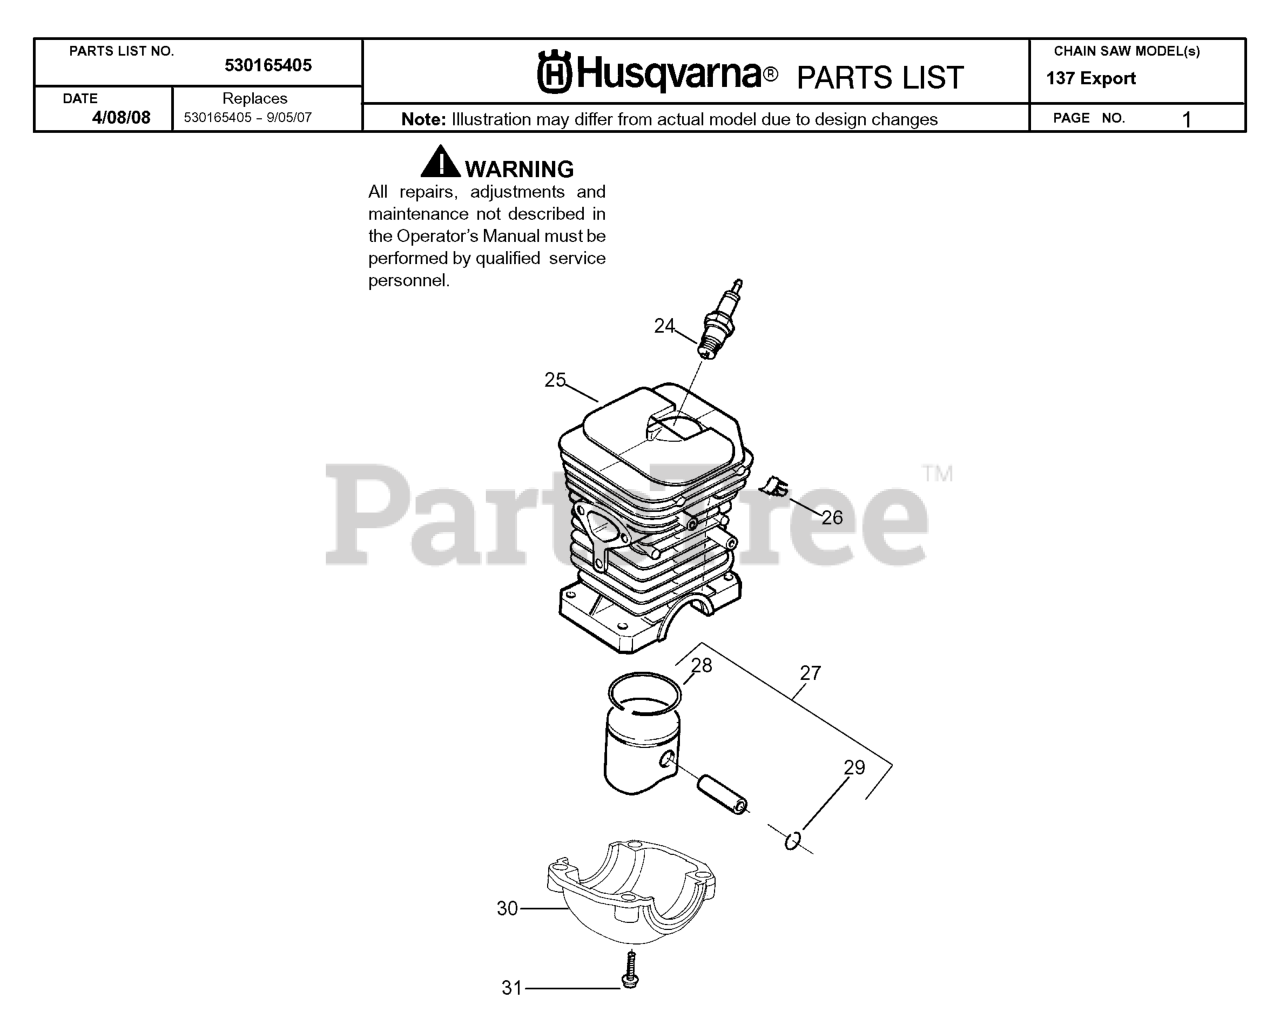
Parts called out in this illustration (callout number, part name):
24	Spark Plug (RCJ--7Y)
25	CYLINDER ASSY/136
26	CLIP - HIGH TENSION LE
27	PISTON KIT/136
28	PISTON RING 36
29	C-CLIP,PSTN PIN 36/41
30	CAP-CRANKSHAFT
31	SCREW-M5-0.8 X 25MM(TAP)
